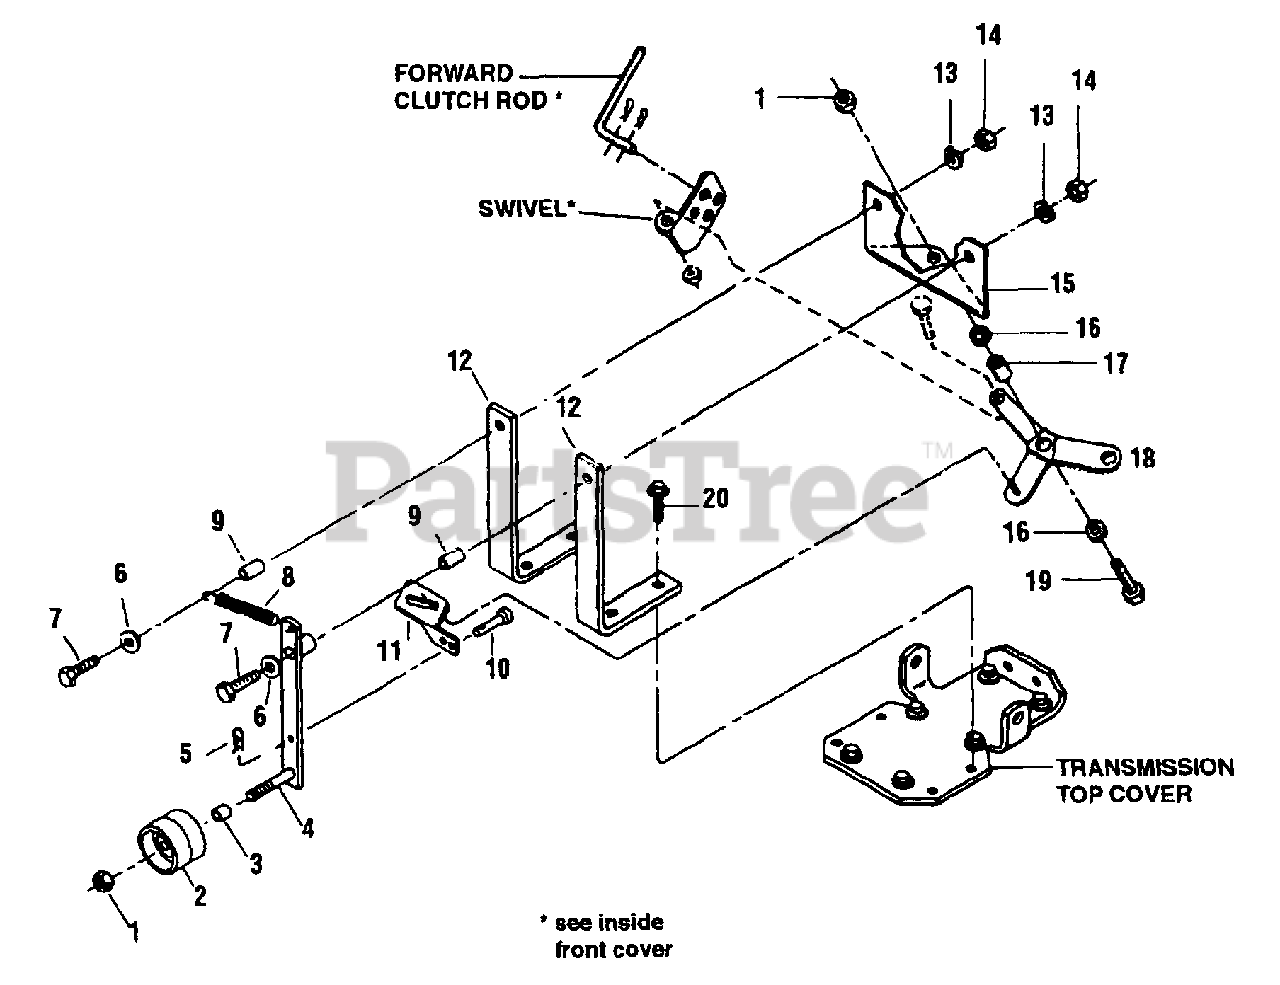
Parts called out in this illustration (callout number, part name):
1	Locknut-hex, 3/8-16
2	Pulley-idler, forward tiller
3	Spacer
4	Idler Arm-left, forward tiller direction
5	Hairpin Cotter
6	Washer-plain, 5/16
7	Screw-hex hd., 5/16-18 x 2-1/4
8	Spring
9	Pivot Bushing
10	Pin
11	Forward Link
12	Mounting Bar
13	Lockwasher-5/16
14	Nut-hex, 5/16-18
15	Shifting Base
16	Spacer-Bushing
17	Bushing-bellcrank
18	Bellcrank
19	Screw-hex hd., 3/8-16 x 1-1/4
20	Screw-flanged hex hd., 5/16-18 x 1
